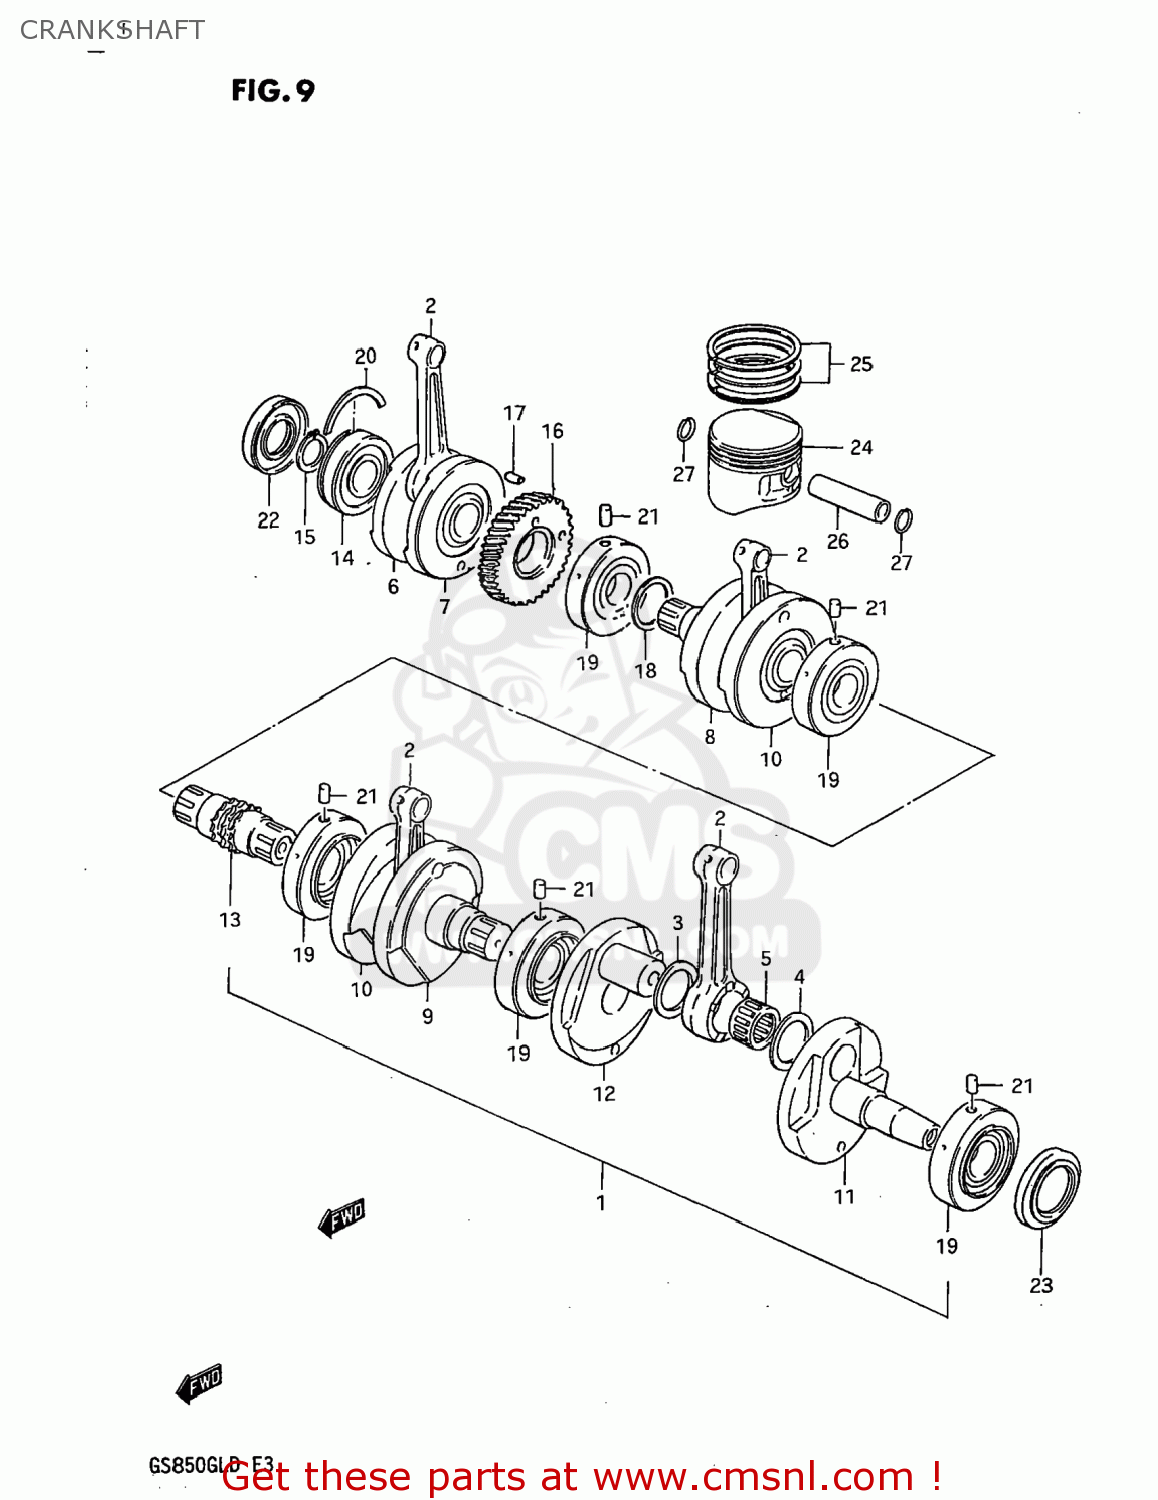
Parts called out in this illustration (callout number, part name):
1	CRANKSHAFT ASSEMBLY
2	ROD,CONNECTING
3	WASHER (29X48X2)
4	WASHER (29X48X1)
5	BEARING(29X39X20)
6	CRANKSHAFT
7	WEB,CRANK,RIGHT
8	CRANKSHAFT
9	CRANKSHAFT, MIDDLE LH
10	WEB,CRANK,MIDDLE
11	CRANKSHAFT,LEFT
12	WEB,CRANK,LEFT
13	SHAFT,TIMING CHAIN DRIVE
14	BEARING(30X72X19)
15	CIRCLIP,30MM
16	GEAR,PRIMARY DRIVE
17	PIN
18	WASHER
19	BEARING
20	C RING
21	PIN
22	SEAL,OIL(30X72X11)
23	OIL SEAL
24	PISTON
25	RING SET,PISTON
26	PIN,PISTON
27	CIRCLIP
